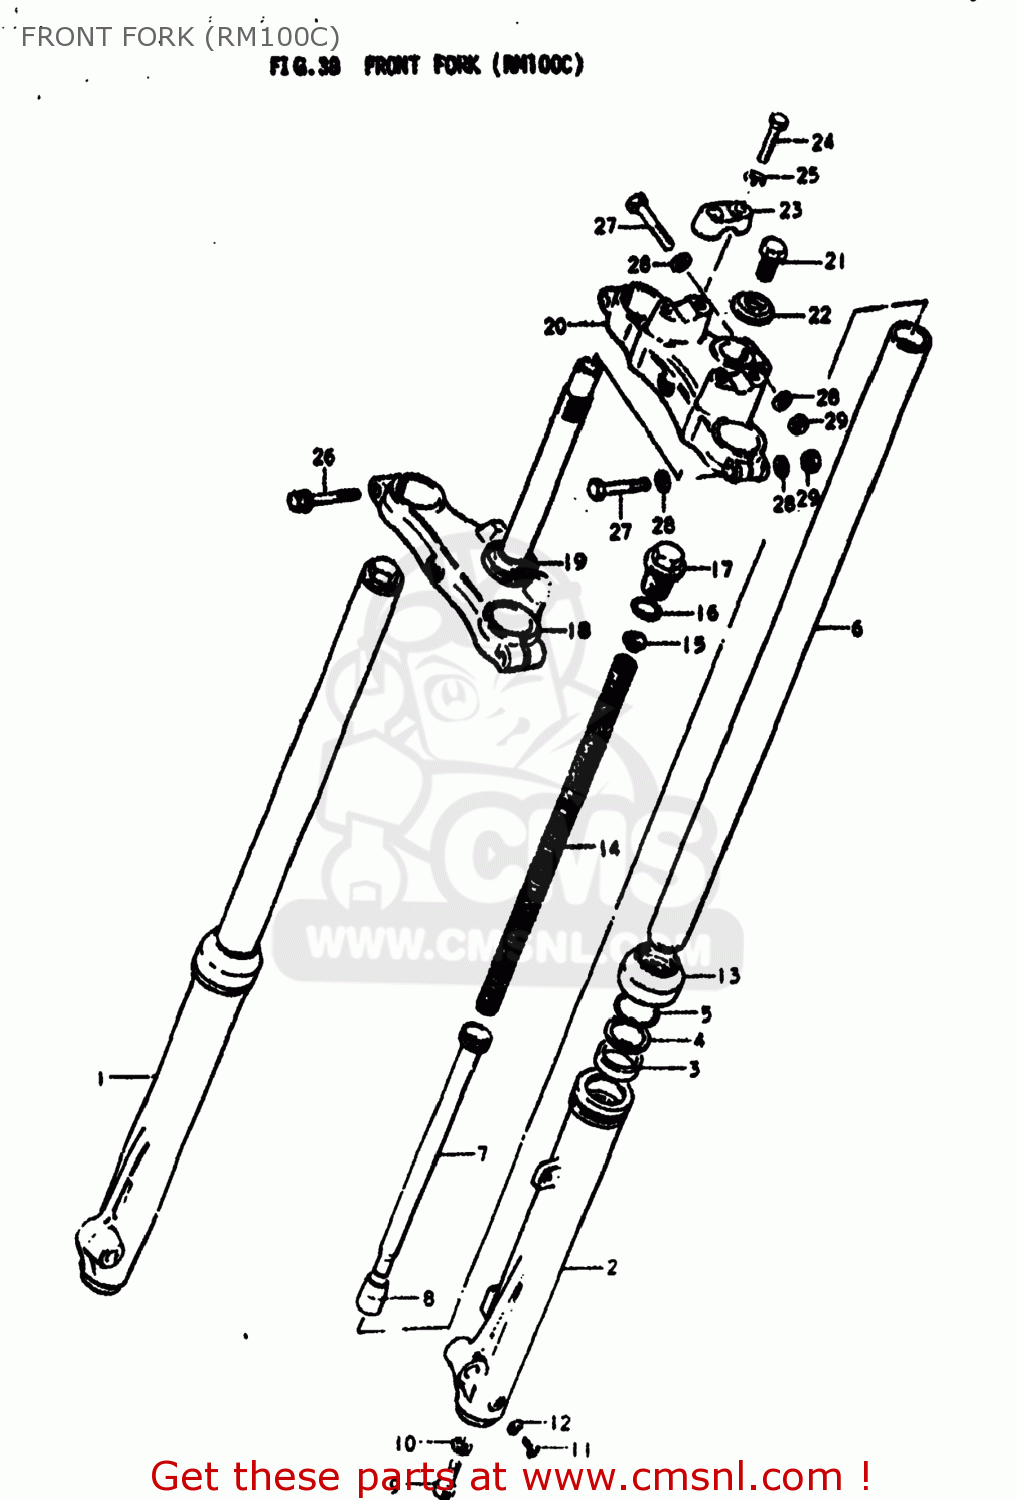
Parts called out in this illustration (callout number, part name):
1	TUBE,OUTER,RIGHT
2	TUBE,OUTER,LEFT
3	OIL SEAL,FRONT FORK
4	WASHER
5	RING,SNAP
6	TUBE,FORK,INNER
7	CYLINDER,FRONT FORK
8	PIECE,OIL LOCK
9	BOLT,FORK CYLINDER(10X25)
10	GASKET (NAS)
11	SCREW
12	GASKET,DRAIN,PLUG (NAS)
13	SEAL,DUST
14	SPRING
15	GUIDE,SPRING COVER
16	O-RING,FORK INNER TUBE
17	CAP
18	STEM,STEERING
19	RACE,STEERING OUTER LWR
20	HEAD,STEERING STEM
21	BOLT
22	WASHER
23	HOLDER,HANDLEBAR
24	BOLT
25	LOCK WASHER
26	BOLT,FORK INNER TUBE F
27	BOLT 8X55
28	WASHER
29	NUT
